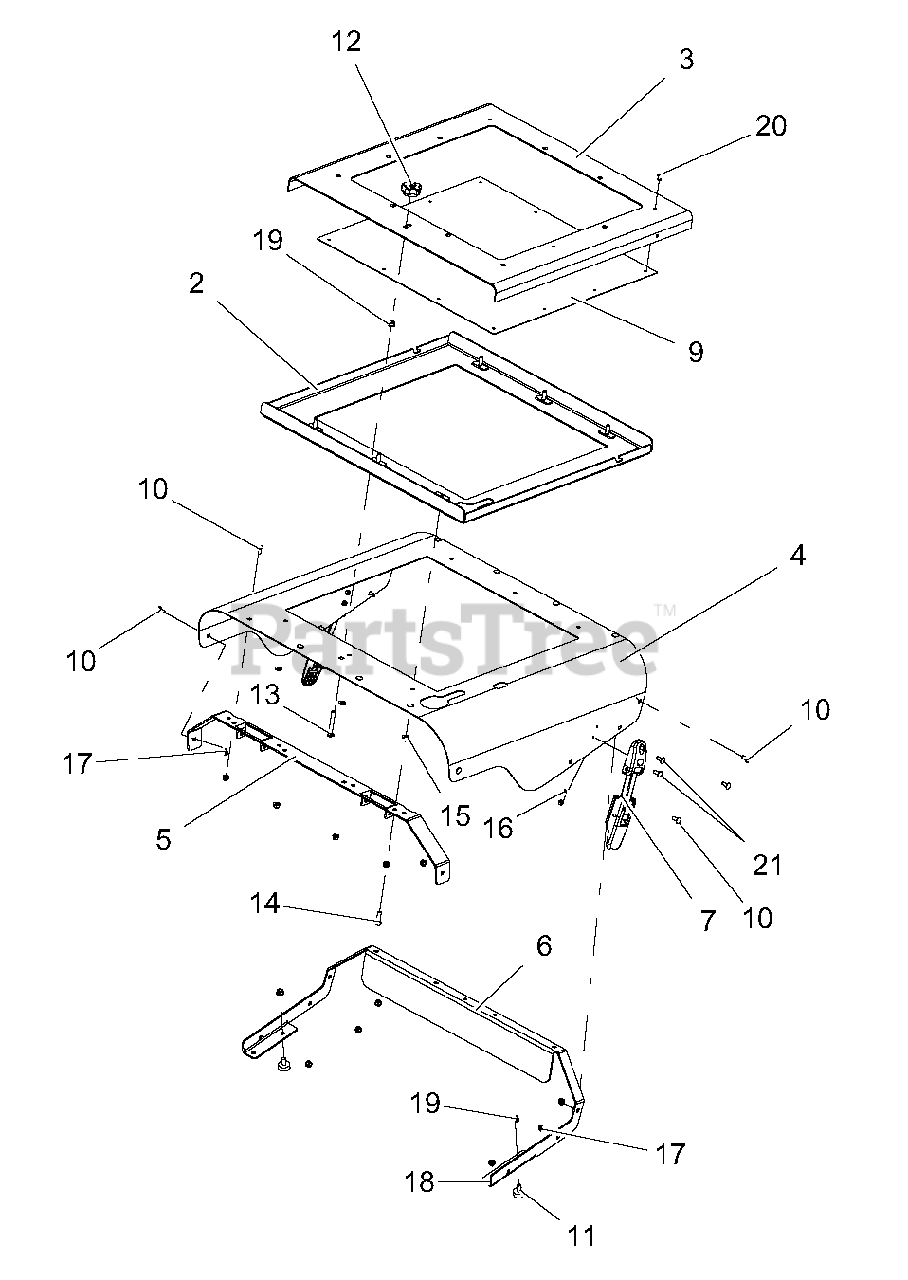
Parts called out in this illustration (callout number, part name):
2	WLDMT, HOOD /SCREEN/RAD MOUNT-BLACK
3	WLDMT, SCRN MOUNT-RED
4	HOOD, PT400 DIESEL
5	SUPPORT, DIESEL HOOD FRONT
6	SUPPORT, RADIATOR HOOD REAR
7	LATCH, O/C RUBBER
9	SCRN, DIESEL RADIATOR
10	BLT, RDHDSQNK .25-20 X .625 YWZC RED HEAD
11	BUMPER, RUBBER
12	KNOB, CLAMPING
13	@BLT-RDHDSQNK .31-18X2.25 G5 Y
14	BLT-HEX .31-18X1.00 GR5 YWZC
15	@WSHR-LK .31X.078 REG YWZC
16	@NUT-LK-NYL #10-24 YWZC
17	NUT-LK-NYL-FLG .25-20 YWZC
18	NUT-LK-NYL-FLG .31-18 YWZC
19	@NUT-SPNLK-FLG .312-18 YWZC
20	RVT-POP .187x.375 (#66) BLACK
21	@SCR-MCH 10-24X.50 HWH YWZC
